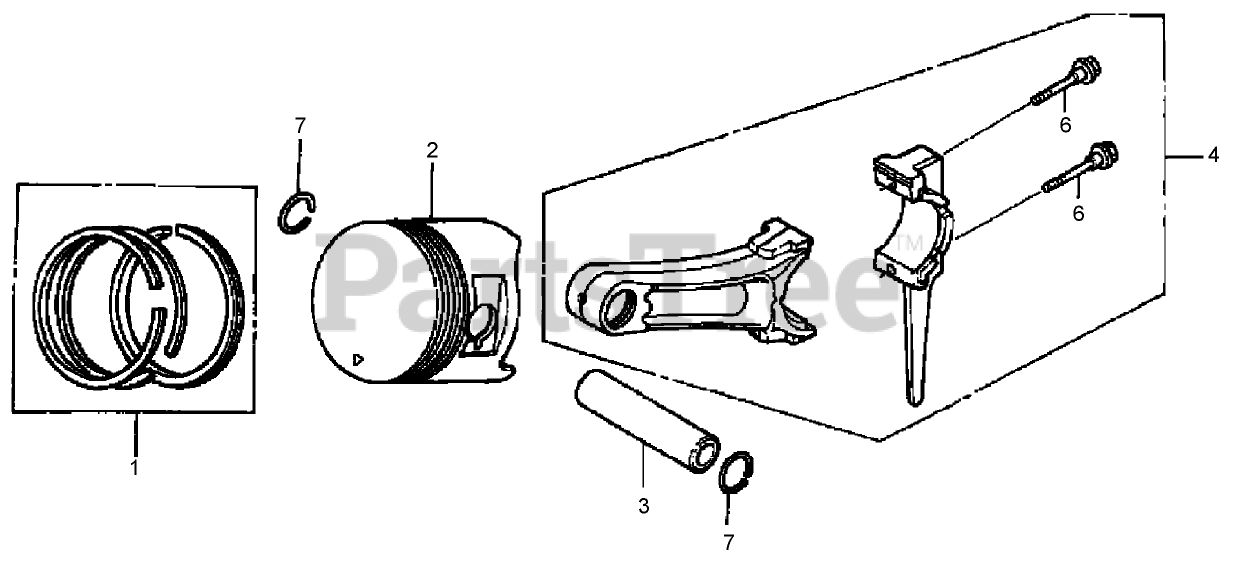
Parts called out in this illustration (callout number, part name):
1	RING SET, PISTON (STD)
1	RING SET, PISTON (OS 0.25)
1	RING SET, PISTON (OS 0.50)
1	RING SET, PISTON (0.75) (NIPPON)
2	PISTON (STD)
2	PISTON (OS 0.25)
2	PISTON (OS 0.50)
2	PISTON (0.75)
3	PIN, PISTON
4	ROD ASM-CONNECTING (STD)
4	ROD ASM-CONNECTING (US 0.25)
6	BOLT-ROD, CONNECTING
7	CLIP-PIN, PISTON (20MM)
